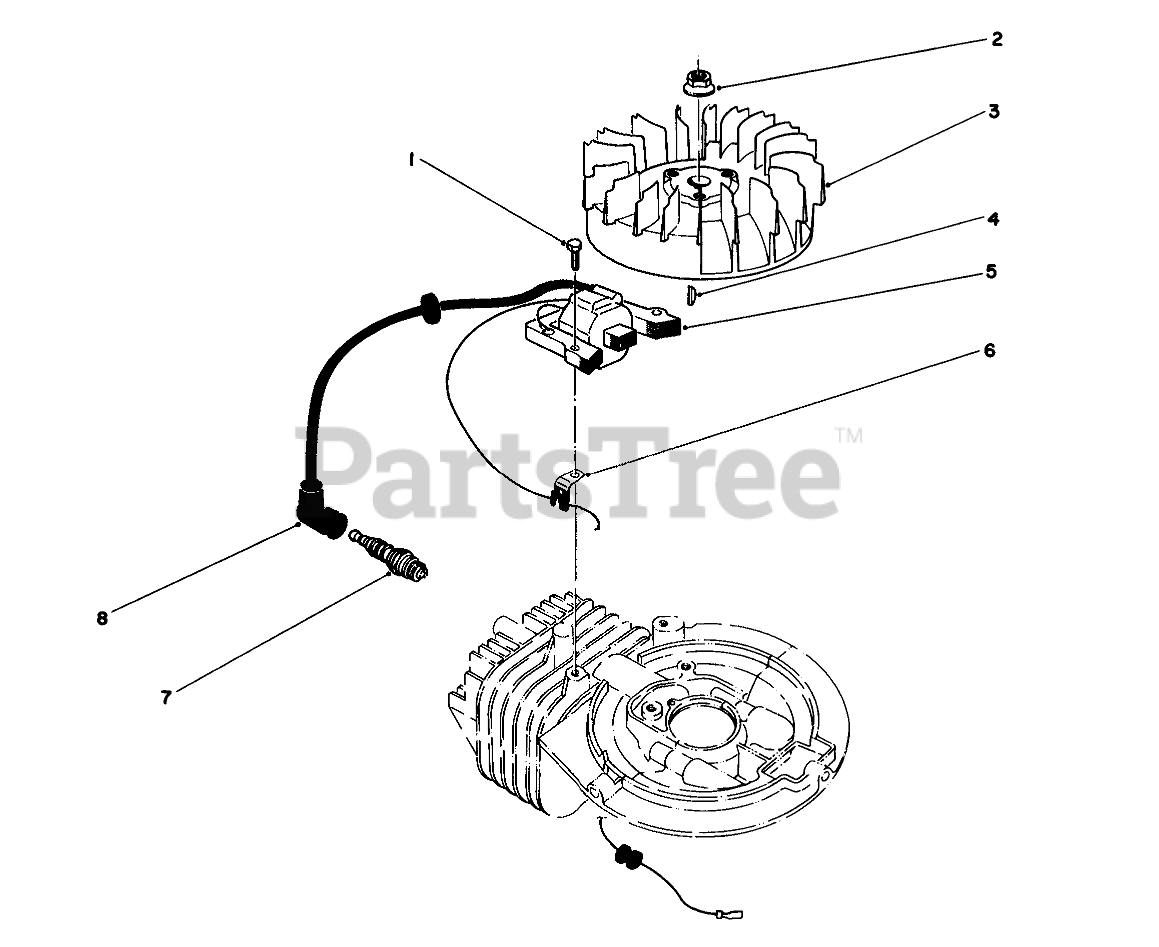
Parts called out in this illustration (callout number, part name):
1	SCREW
3	FLYWHEEL
5	COIL-MAGNETO
6	CLAMP
7	Sparkplug
8	CAP-SPARKPLUG
